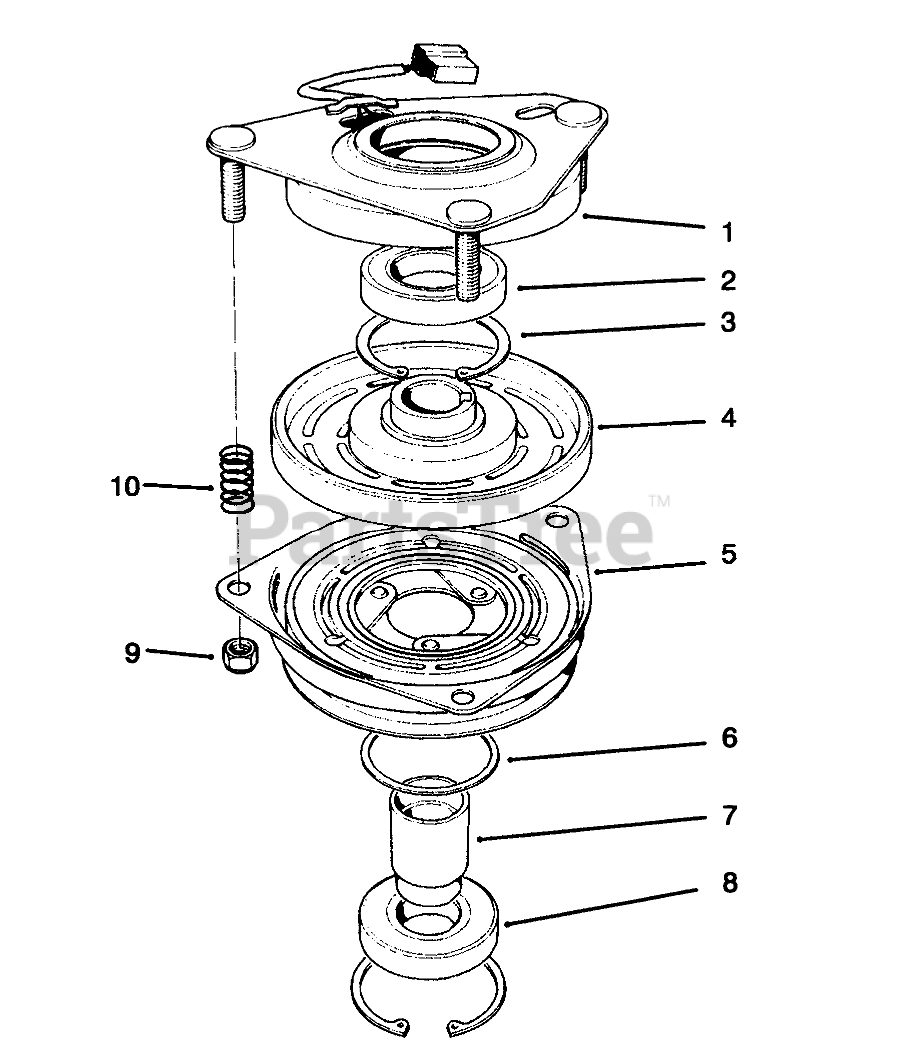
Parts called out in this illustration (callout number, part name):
1	Field Assembly (Incl. Ref. #2 & 3)
2	BEARING-FIELD
3	RING-RETAINING
4	Field Coil, Rotor & Bearing Assembly (Incl. Ref. #1)
5	Armature & Pulley Assembly (Incl. Ref. #3, 6, 7, & 8)
6	SPACER-BEARING, PULLEY
7	COLLAR-BEARING
8	BEARING-PULLEY
9	NUT-HEX
10	SPRING
